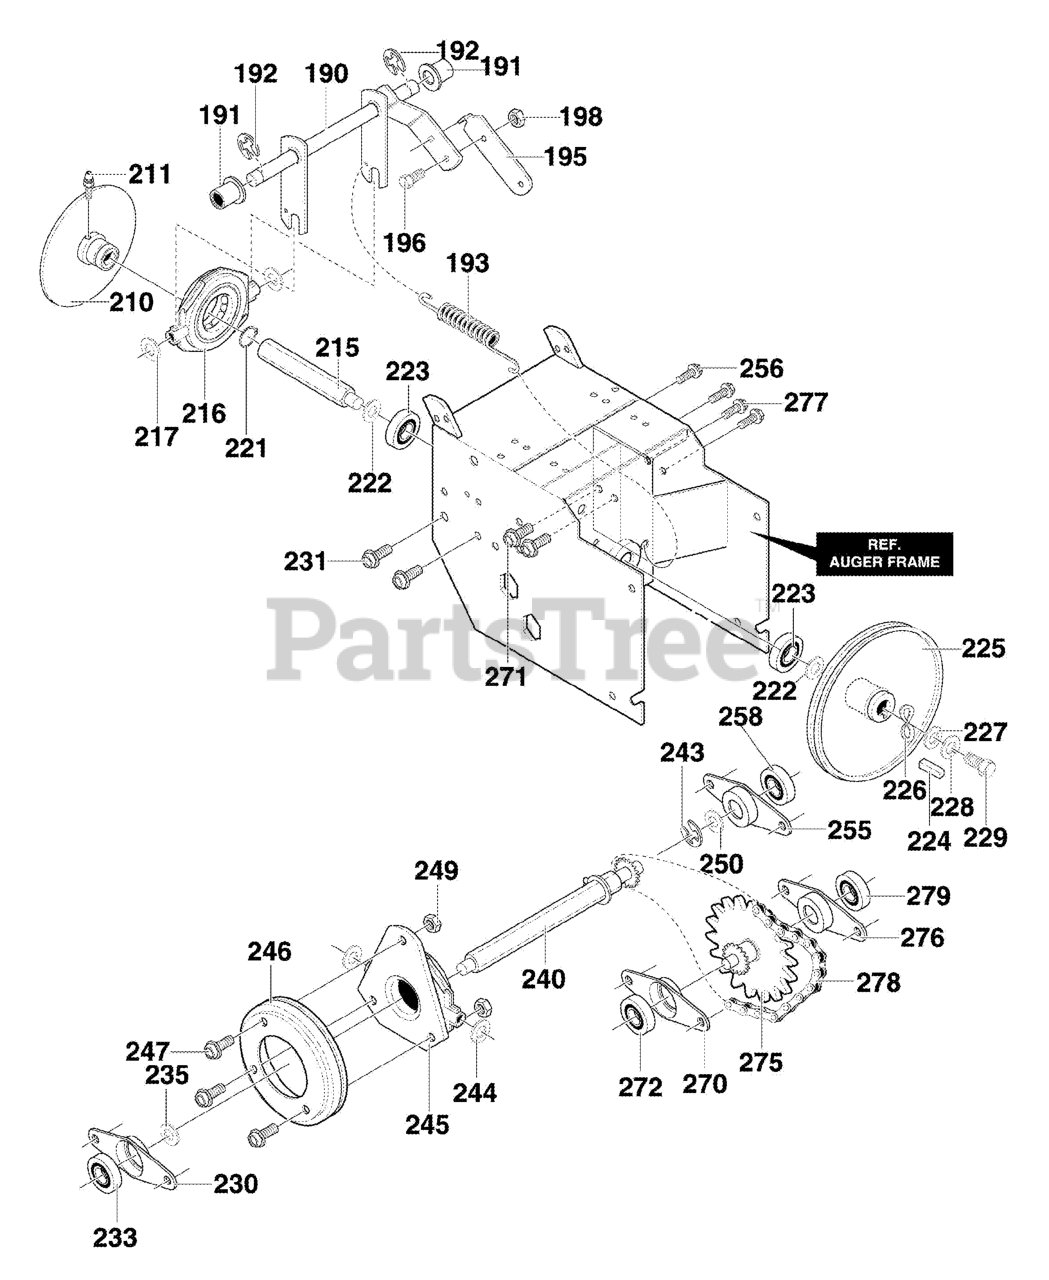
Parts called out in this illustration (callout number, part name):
190	LEVER, ASSY TRACTION CLUTCH
191	BEARING, FLANGE
192	RING, RET E
193	SPRING, RETURN
195	LEVER, SPRING
196	SCREW, 1/4-20X .63
198	NUT, 1/4-20
210	DISC, ASSY
211	ZERK, GREASE
215	SHAFT, HEX TRACTION
216	BEARING, TRUNION
217	FLATWASHER
221	RING, RETEX
222	FLATWASHER
223	BEARING, BALL
224	KEY, SQUARE
226	WASHER, WAVE
227	FLATWASHER
228	WASHER, SPLIT
230	BEARING & RETAINER
231	SCREW, 5/16-18 x 0.50
233	BEARING, BALL
240	ASSEMBLY, HEX SHAFT
243	RING, RETEX
244	FLATWASHER
245	BEARING, TRUNION
246	WHEEL, ASSY FRICTION
247	SCREW, 1/4-20X .63
249	NUT, 1/4-20 KEPS
255	BEARING & RETAINER
256	SCREW, 5/16-18 x 0.50
258	BEARING, BALL
270	BEARING & RETAINER
271	SCREW, 5/16-18 x 0.50
272	BEARING, BALL
275	ASSEMBLY, JACKSHAFT
276	BEARING & RETAINER
277	SCREW
278	CHAIN ROLLER
279	BEARING, BALL
